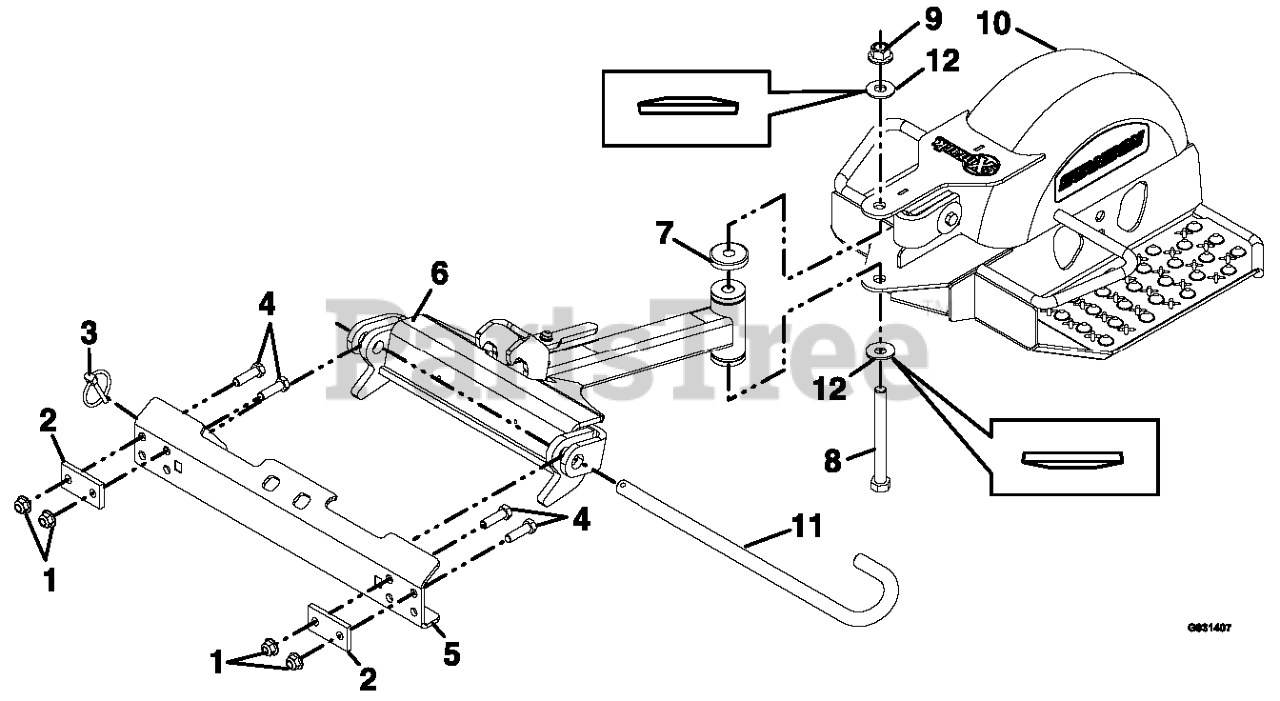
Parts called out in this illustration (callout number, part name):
1	Nut, Nyloc 3/8-16 Flg
2	Plate, Back-Up
3	Pin-Lynch
5	Asm-Mount Plate W/Decals
6	Asm-Drawbar W/Brgs and Decal
7	Cover-Dust
10	Asm-Sulky Frame W/Decals
11	Pin-Pivot
12	Washer-Spring Disc
